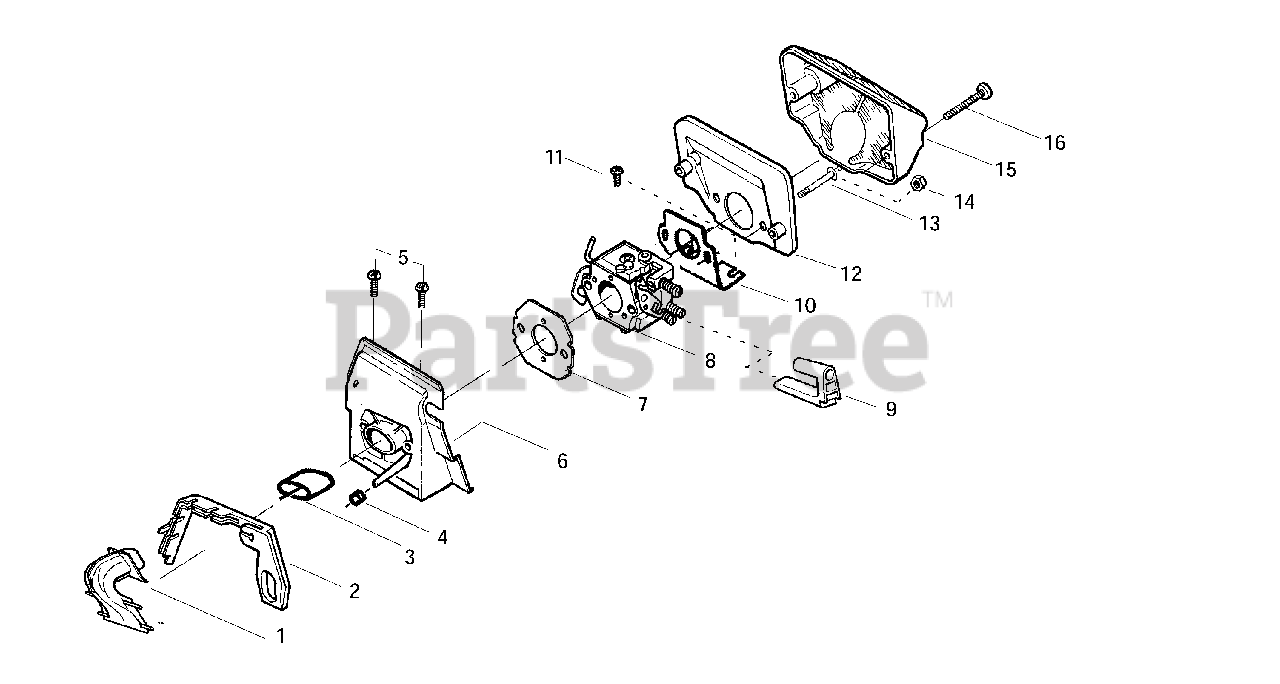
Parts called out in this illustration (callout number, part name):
1	Turbo Air Cleaner Assembly
2	Seal - Turbo Clean
3	Intake Sleeve
4	Impulse Seal
6	Adapter - Carb.
7	Carburetor Gasket
8	Carburetor WT-542 (Walbro)
8	Carburetor WT-289 (Walbro)
8	Carburetor WT-540 (Walbro)
9	Grommet-Final
10	Plate - Support
12	Air Filter - Bottom
13	Stud - Carb.
15	Air-Filter - Top
